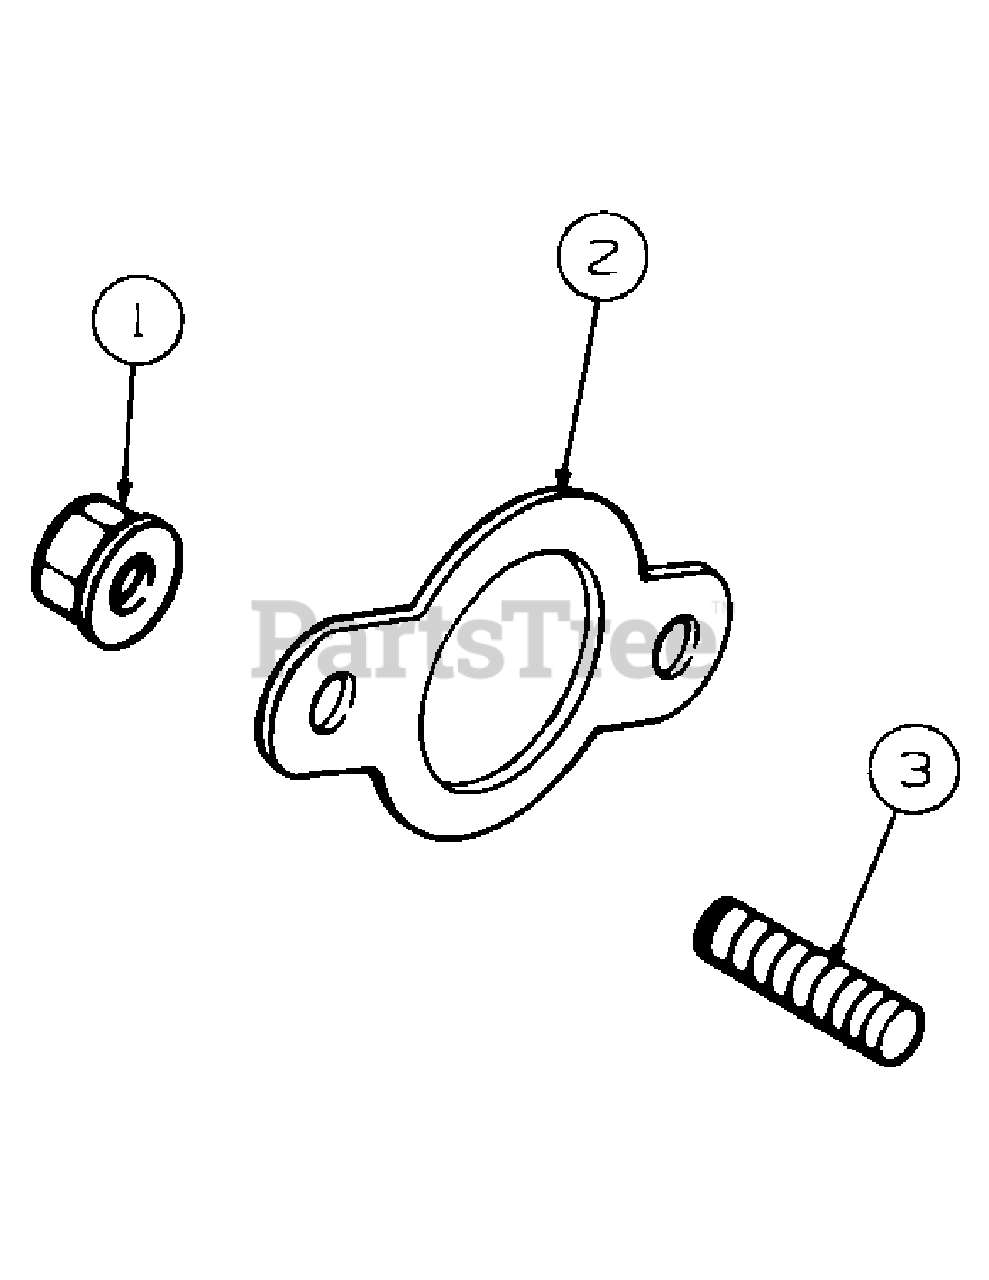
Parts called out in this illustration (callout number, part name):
1	Nut, Muffler Mounting, M8 x 1.25
2	Gasket, Exhaust
3	Stud, Exhaust, M8 x 1.25 x 33
